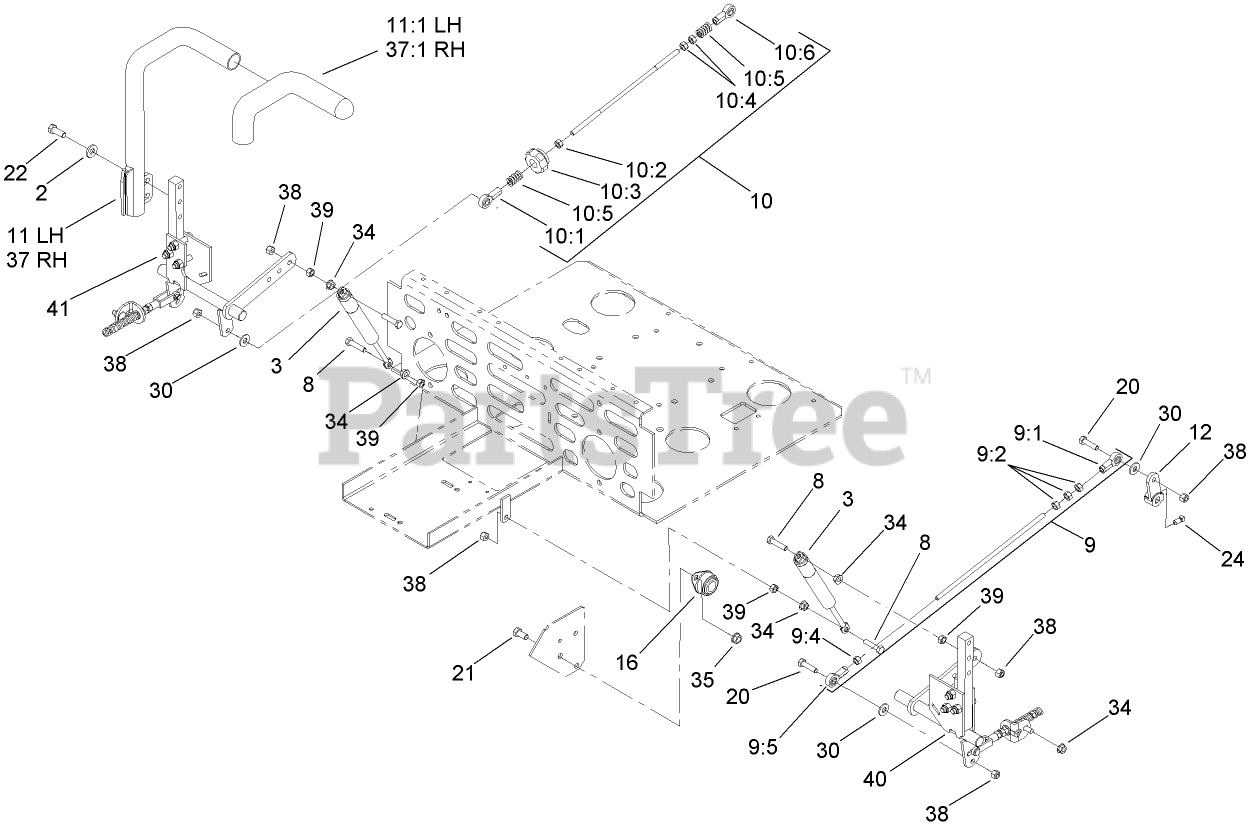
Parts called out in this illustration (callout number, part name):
2	WASHER-BELLEVILLE
3	DAMPER-CONTROL, MOTION
8	SCREW-HH
9	Tracking Rod ASM
9:1	BALLJOINT-RH
9:2	NUT-HEX
9:5	BALLJOINT-LH
10	Tracking Rod ASM
10:1	BALLJOINT-RH
10:2	NUT-HEX
10:3	KNOB-TRACKING
10:5	SPRING-COMPRESSION
10:6	BALLJOINT-LH
11	LH LEVER ASM
11:1	Grip-Control, Motion
12	ARM-CONTROL, PUMP
16	BEARING-FLANGE, SIDE
20	SCREW-HH
21	SCREW-HH
22	SCREW-HH
24	SCREW-SET
30	WASHER-FLAT
34	NUT-HF
35	NUT-HHF, WHIZ
37	RH LEVER ASM
37:1	Grip-Control, Motion
38	NUT-LOCK, NI
39	NUT-HEX
40	LH MOTION CONTROL ASM
41	RH MOTION CONTROL ASM
